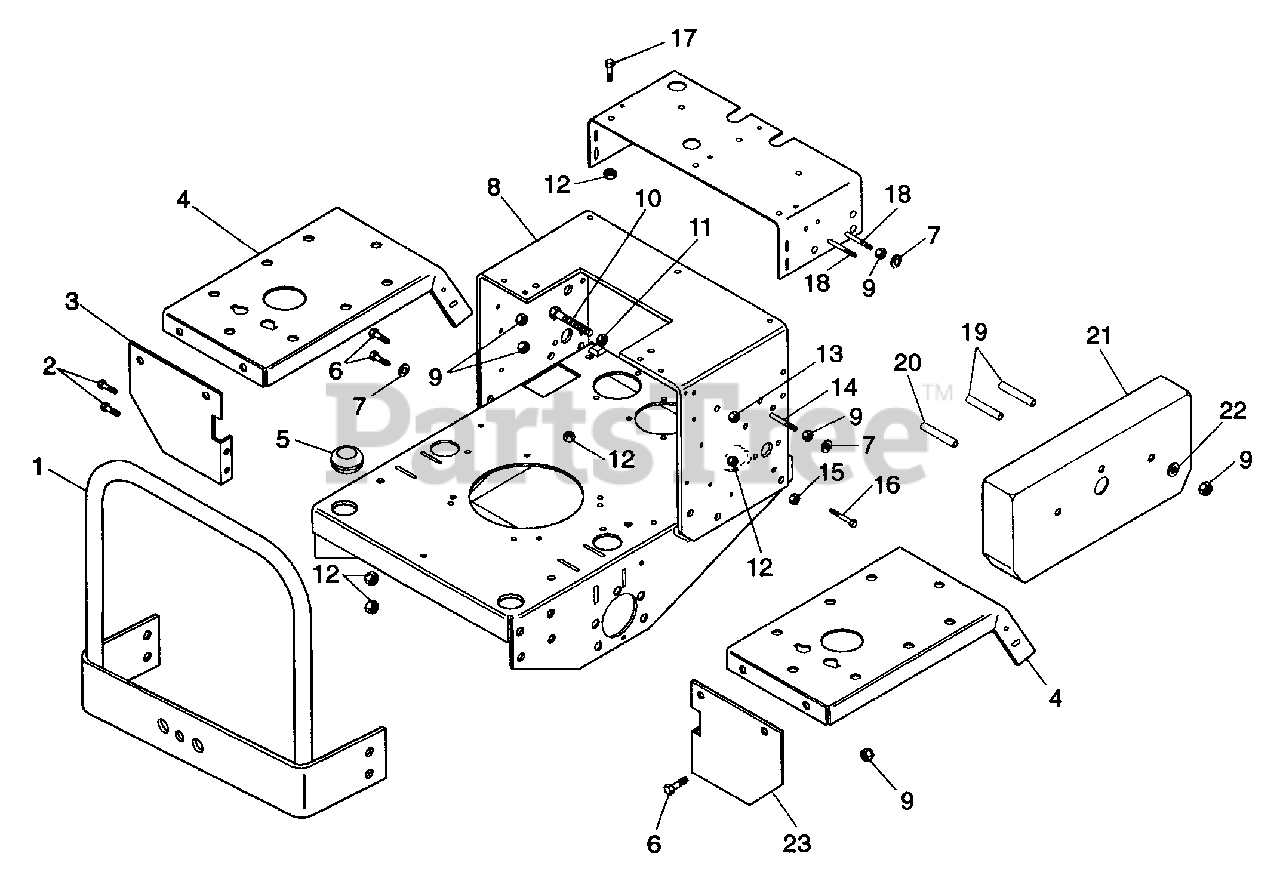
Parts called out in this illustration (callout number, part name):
1	WELDMT, REAR GUARD
2	BLT-HEX .38-16 X 1.25 PL GR 5
3	SPRT, FENDER L.H.
4	FENDER
5	GROMMET
6	BLT-HEX .31-18 X .75 PL GR 5
7	WSHR-FL-STL .344 X .688 X .065
8	WLDMT, FRAME
9	NUT-LK-NYL .312-18 PL
10	BLT-HEX .25-20 X 3.00
11	NUT-HEX .25-20
12	NUT-LK-NYL .375-16 PL
13	NUT-LK-NYL .250-20 W/INSR
14	BLT-HEX .312-18 X 3.75
15	NUT-HEX .375-16
16	BLT-HEX .38-16 X 3.00
17	BLT-HEX .38-16 X 1.00 GR 5
18	BLT-HEX .312-18 X 4.00
19	SPACER, .328 X .462 X 2.75
20	SPACER, .328 X .462 X 2.50 LG
21	GUARD LINKAGE
22	WSHR-FL-STL .313 X .875 X .065
23	SPRT, FENDER R.H.
